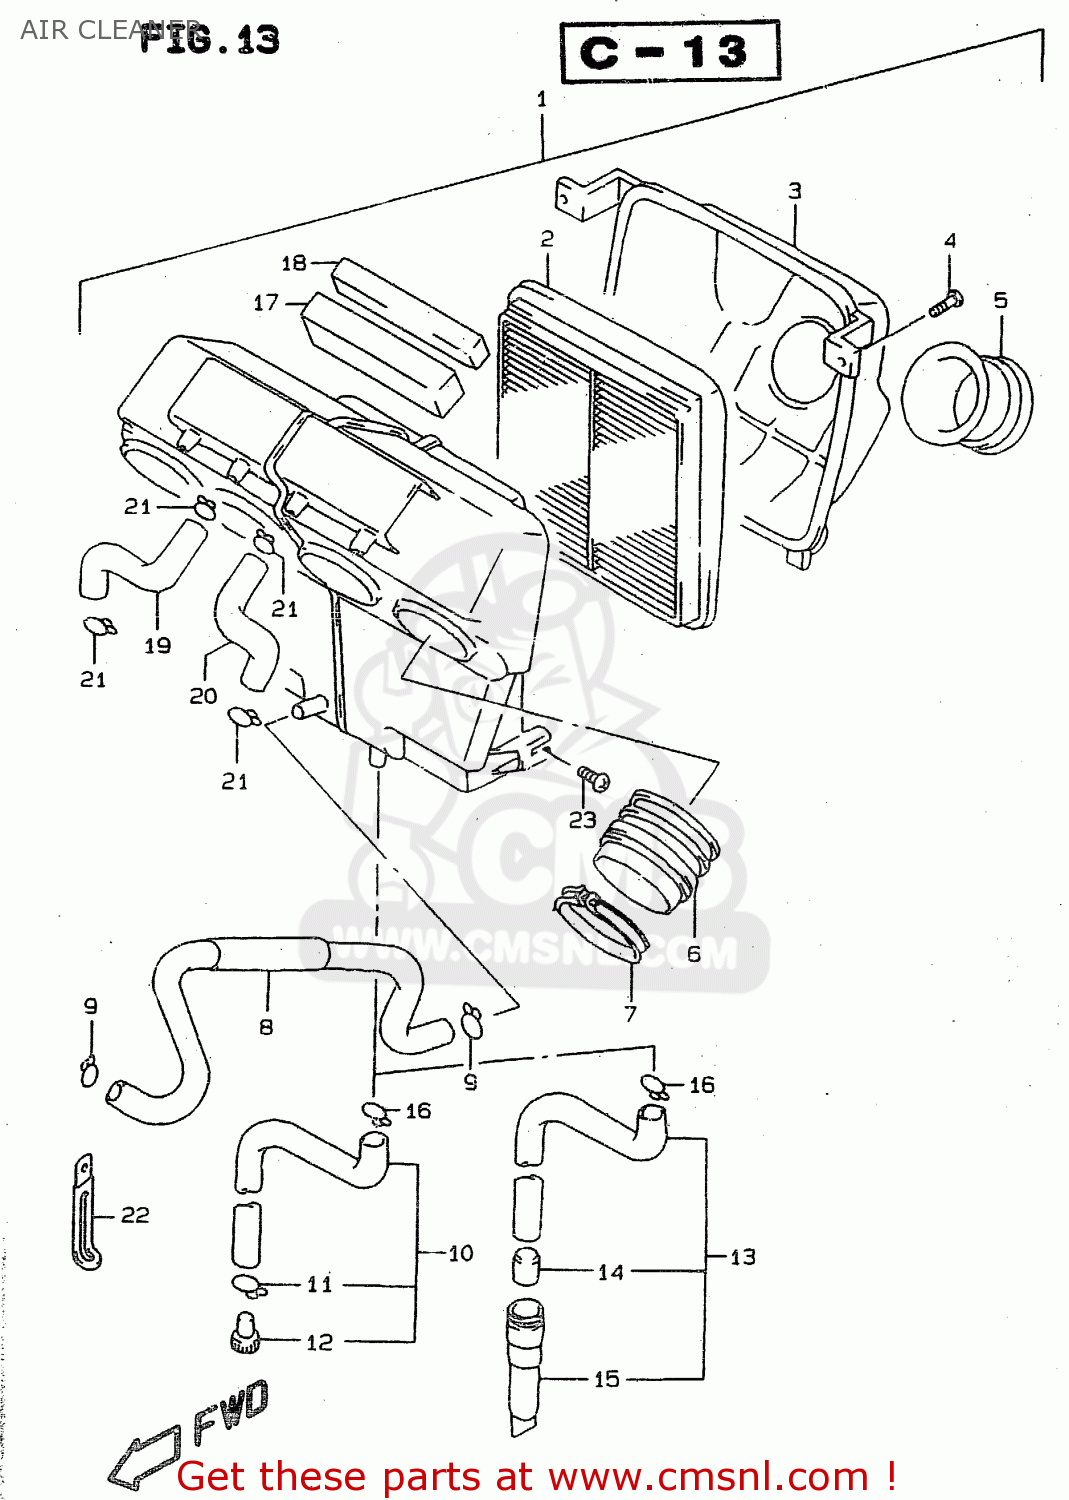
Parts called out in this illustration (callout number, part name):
1	CLEANER ASSY, AIR
2	FILTER,AIR
3	CAP,AIR CLEANER
4	SCREW
5	TUBE,INLET
6	TUBE,OUTLET
7	CLAMP
8	TUBE,BREATHER
9	CLIP
10	TUBE,DRAIN
11	CLIP
12	STOPPER,DRAIN
13	TUBE,DRAIN
14	FILTER,DRAIN
15	CAP,DRAIN
16	CLIP
17	FILTER,CARB AIR
18	FILTER,AIR NO.2
19	TUBE,CARBURETOR AIR,R
20	TUBE,CARBURETOR AIR,LEFT
21	CLIP
22	CLAMP(L:80)
23	SCREW 6X12
